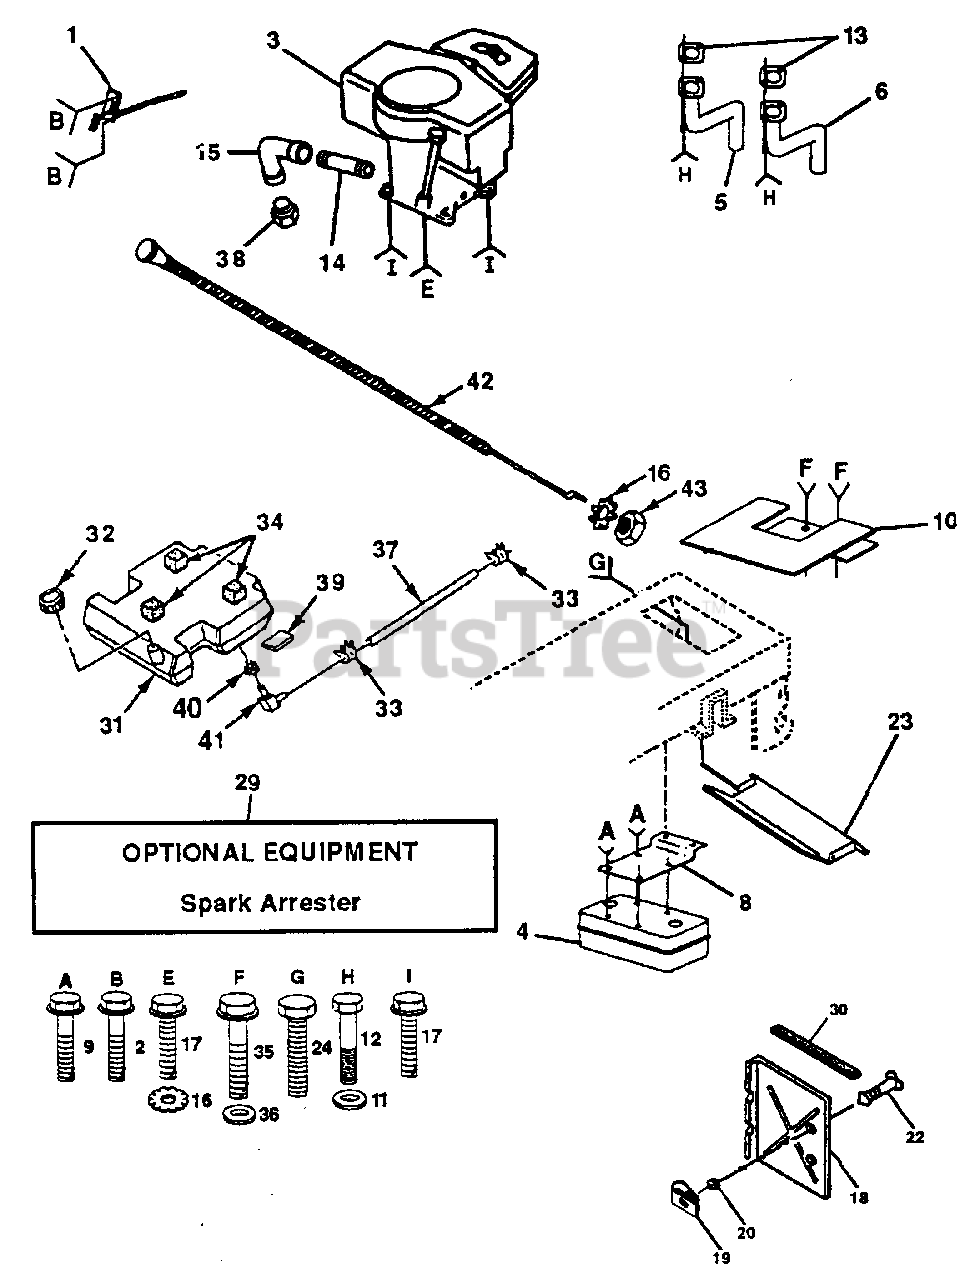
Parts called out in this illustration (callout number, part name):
1	Control RH Blk Flg 37 88
2	Screw Hex Thd Cut 1/4-20x5/8 T
4	Muffler VGT YT Dual Inlet
5	Tube Manifold LH
6	Tube Manifold RH
8	Bracket Muffler Mounting
9	Screw Hex Wsh Thd Cut 1/4-20
10	Shield Heat LT
11	Washer Lock Hvy Spr 5/16-18
12	Screw Hex Skt 5/16-18 unc x 3/4
14	Nipple Pipe 3/8 Npt X 4-1/2"
15	Elbow Std 90 Degree 3/8-18 Npt
16	Washer Lock Ext Tooth 3/8
17	Screw Thdrol 3/8-16 x 1-1/2
18	Shield Heat Electric
19	Receptacle 1/4 Turn
20	Retainer 1/4 Turn
22	Stud 1/4 Turn
23	Shield Heat Browning LT/YT
24	Screw Tap Hex #10-24unc X 1/2
29	Kit Spark Arrestor (Flat Scrn)
30	Foam Strip 18"
31	Tank Fuel 3 50 Rear
32	Cap Asm Fuel
33	Clamp Hose Blk
35	Screw Thdrol 5/16-18 x 3/4
36	Washer 13/32 x 1 x 14 Ga.
37	Line Fuel 54"
40	Bushing
41	Stem Tank Fuel
42	Choke Control
43	Nut, Fin Hex 3/8-24 Unf
